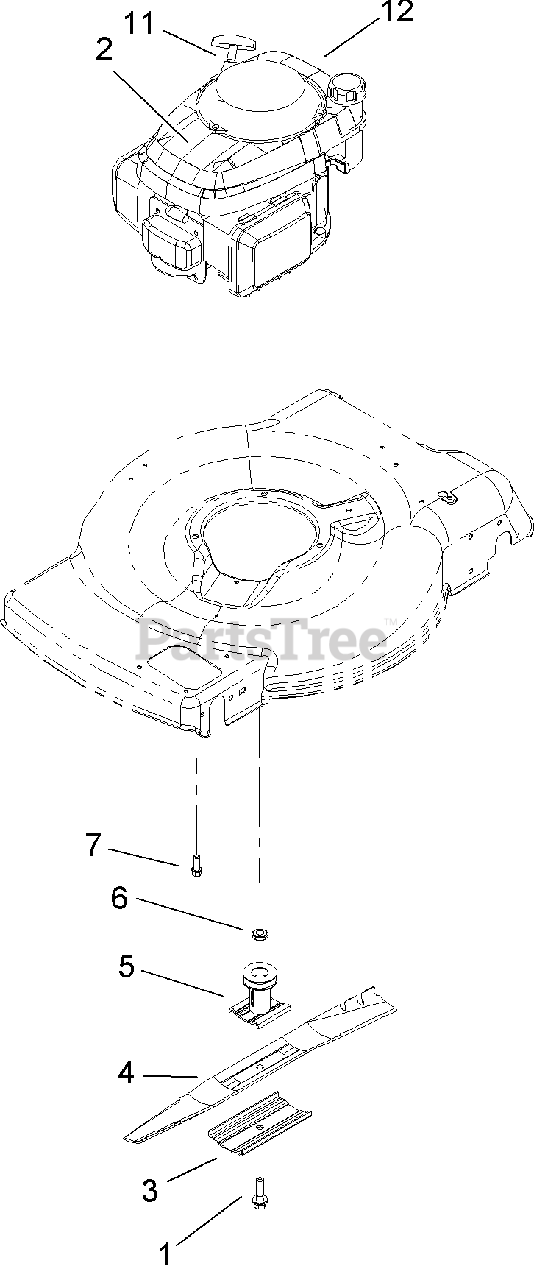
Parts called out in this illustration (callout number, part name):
1	BOLT-BLADE
2	DECAL-RECOIL
3	Support-Blade
4	BLADE-22 INCH
5	BLADE DRIVER ASM
6	Spacer-Driver
7	SCREW-TAPTITE
11	STOP-ROPE
